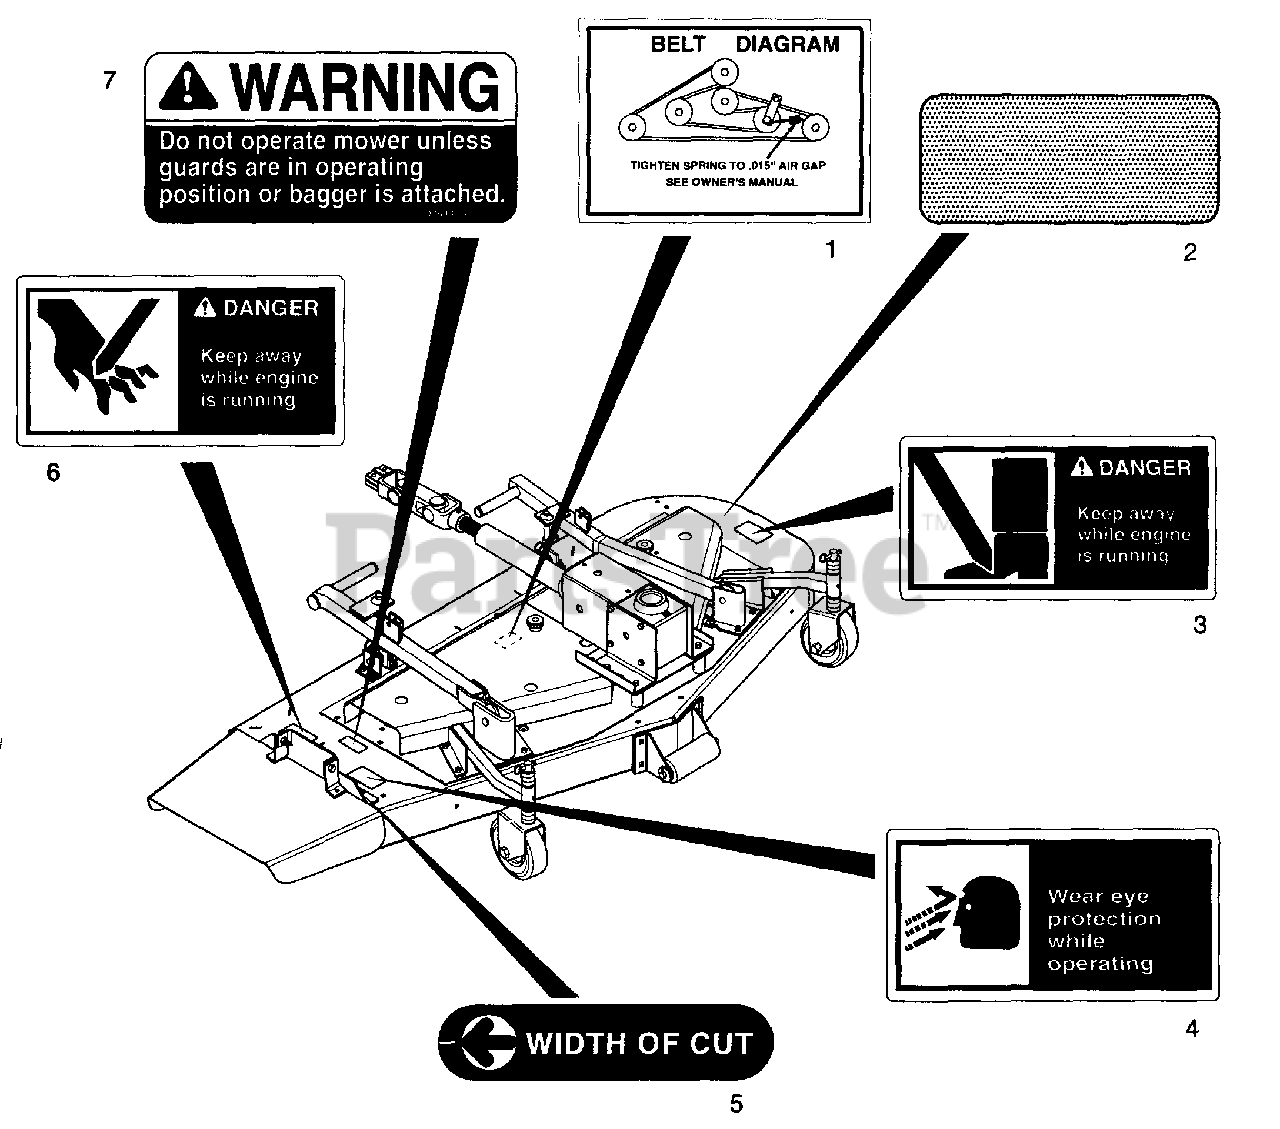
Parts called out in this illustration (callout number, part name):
1	Decal, Belt Diagram
2	Cover, Large Footboard
3	Decal, Danger Foot
4	Decal, Warning Eye
5	Decal, Width of Cut
6	Decal, Danger Hand
7	Decal, Warning
